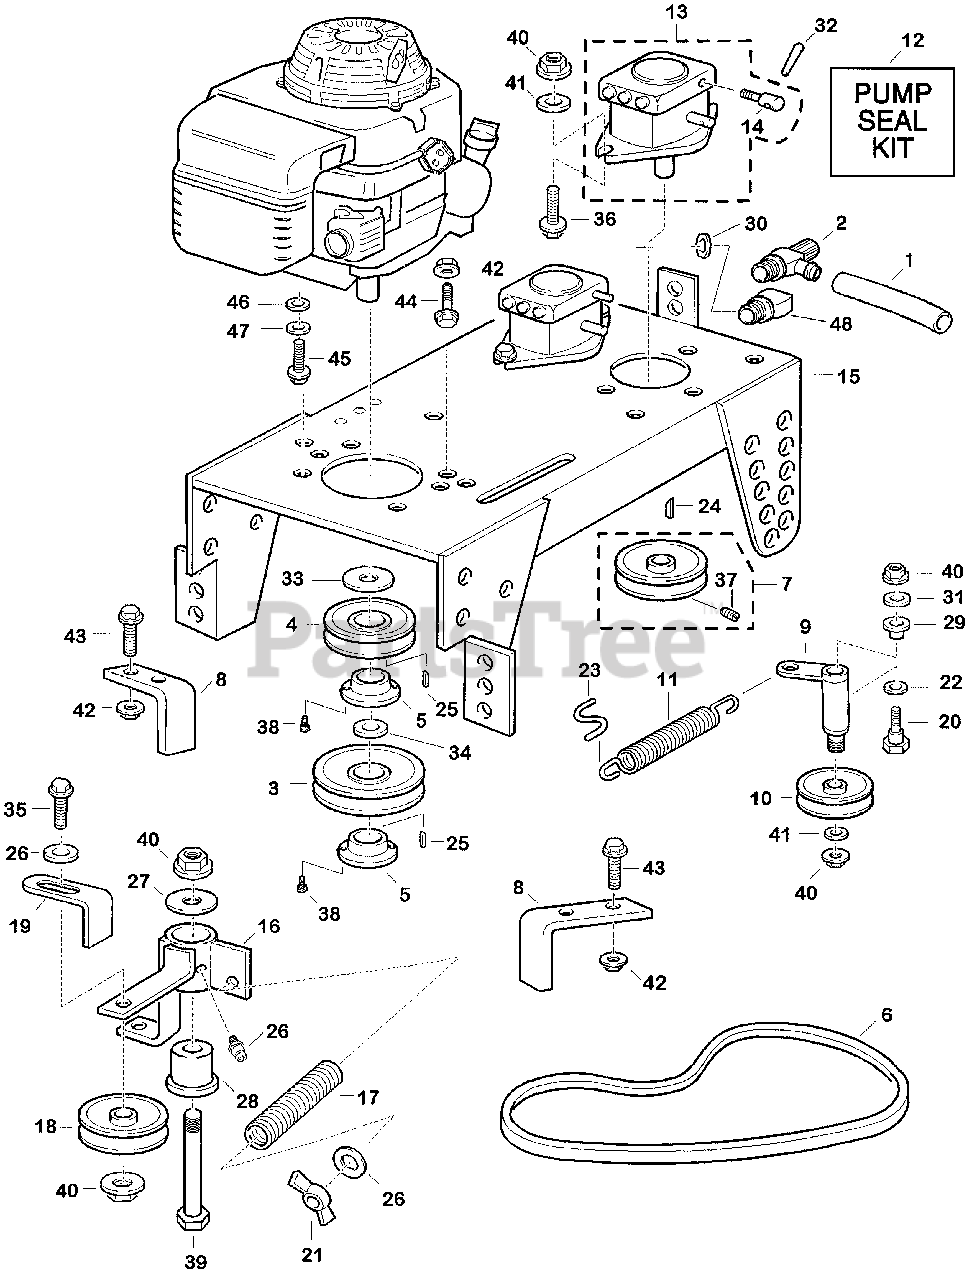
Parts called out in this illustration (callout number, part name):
1	TUBE, OIL DRAIN
2	VALVE, OIL SHUT-OFF
3	PULLEY, DRIVE
4	PULLEY, PUMP DRIVE
5	BUSHING, SPLIT (1")
6	V-BELT, ENGINE PUMP
8	BRACKET, BELT
9	BELLCRANK, IDLER
10	PULLEY, IDLER
11	SPRING, TENSIONER
12	SEAL KIT, PUMP
13	PUMP ASSY., HYDRAULIC
14	VALVE, PUMP BYPASS (KIT)
15	BED, ENGINE
16	ARM, TENSION
17	SPRING, TENSIONER ARM
18	PULLEY A, TENSION
19	GUIDE A, BELT
20	BOLT A, SHOULDER
21	WINGNUT (5/16"-18)
22	WASHER, BELLEVILLE (1/2")
23	CLIP, SPRING
24	KEY, SQUARE (5X5X28)
25	KEY, SQUARE (1/4"X1/4"X1")
26	NIPPLE, GREASE
27	BUSHING (1")
28	BUSHING, PIVOT
29	BUSHING, SNAP
30	WASHER, DRAIN PLUG (20MM)
31	WASHER (5/16")
32	PIN, TAPERED
33	SPACER (7/16")
34	SPACER (1/4")
